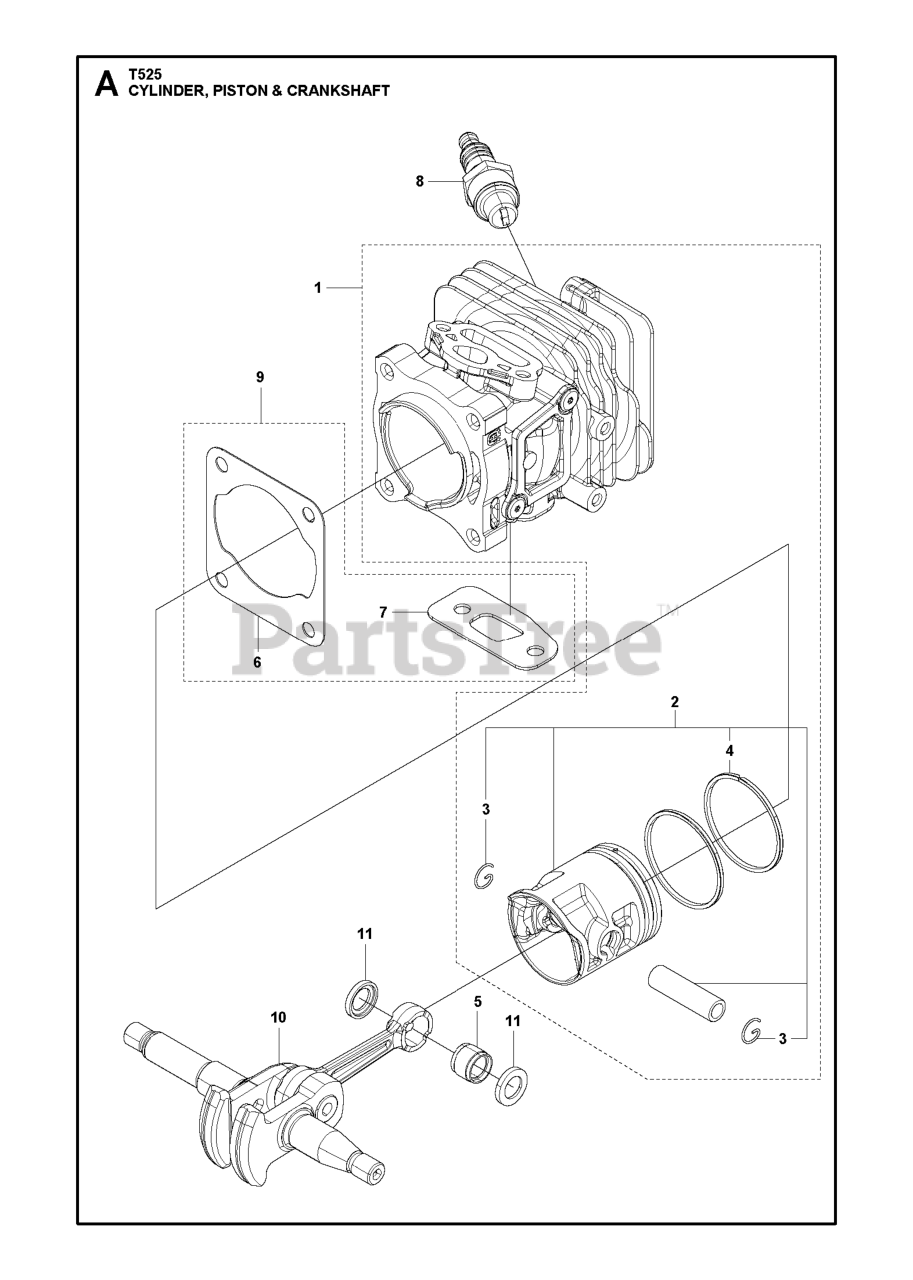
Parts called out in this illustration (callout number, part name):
1	CYLINDER ASSY
2	PISTON ASSY SPARE PART
4	PISTON RING
6	GASKET BASE
7	GASKET MUFFLER
8	SPARK PLUG RESISTOR NGK CMR6A
9	GASKET KIT
10	CRANKSHAFT COMP
